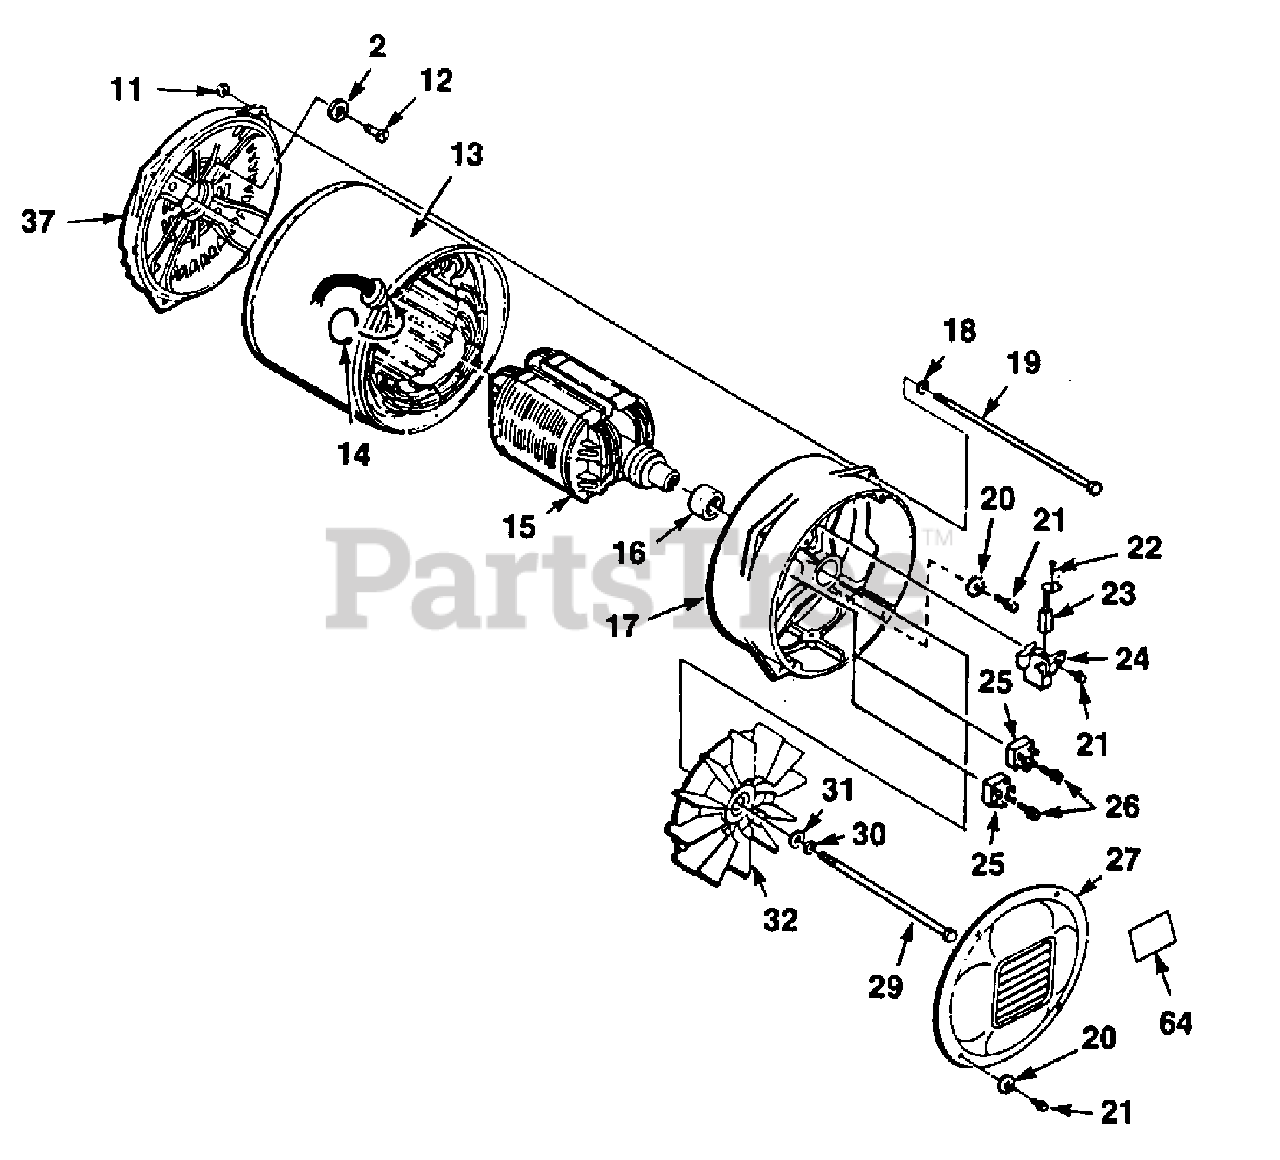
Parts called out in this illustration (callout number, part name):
2	WASHER- Lock Int. 5/16
11	NUT- Hex 1/4-20
12	SCREW- Hex hd., 5/16-24 x 3/4"
13	STATOR & SHELL w/GROMMET
14	TIE- Cable
16	BEARING
17	BRUSH HEAD
18	WASHER- Lock
19	BOLT- Stator
20	WASHER- Lock int. #8
21	SCREW- Thread forming
22	SCREW- Mach round hd. 8-32 x 3/8"
24	BRUSH HOLDER
25	RECTIFIER
26	SCREW- Hex taptite, 8-32 x 3/4"
27	COVER- Brush head
29	BOLT- Rotor .312-24 x 6 1/2"
30	WASHER- Lock 5/16"
31	WASHER- Flat 5/16"
37	END BELL- Generator
64	DECAL- Warning
